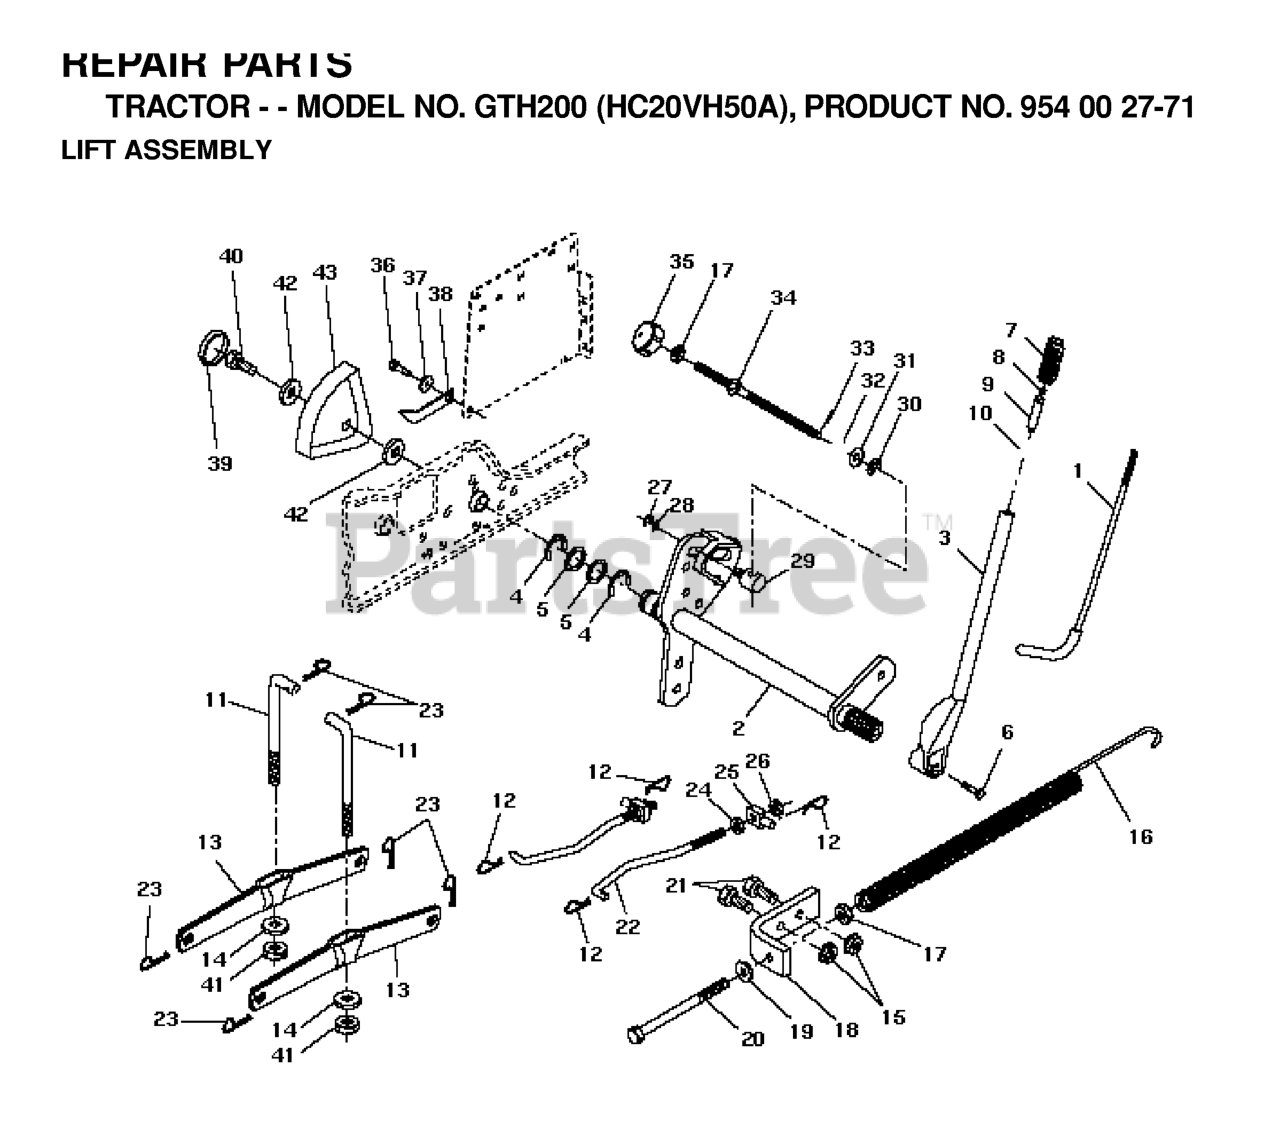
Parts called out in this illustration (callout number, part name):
1	LEVER ROD LT
2	SHAFT ASM, LIFT VGT
3	LIFT LEVER KIT
5	Washer 29/32 x 1 - 1/4 x 16 Ga.
6	BOLT
7	GRIP HANDLE
8	PLUNGER BUT KIT
9	PLUNGER BUT KIT
10	SPRING**
11	LINK LIFT
12	SPRING RETAINER
13	ARM.REAR.SUSPENSION
14	BEARING PIVOT
16	LIFT SPRING
17	NUT
19	WASHER
21	BOLT
22	FRONT LINK
23	RETAINER-SPRNG RB
24	NUT.HEX.JAM.1/2-13
25	TRUNION
26	NUT.LK.W/WSH.1/2.
27	Ring, Klip #T5304-37
28	Washer 15/32 x 3/4 x 16 Gauge
29	TRUNION LT
32	SPRING.COMP.INF.H
33	COTTER PIN
34	ROD.LIFT.ADJUSTABLE
35	KNOB INF 3/8-16
36	SCREW
38	POINTER HGT
40	SCREW.THDROL.5/16-18X3/4.TTY
41	NUT CROWNLOCK 3/8-24
43	HEIGHT INDICATOR
